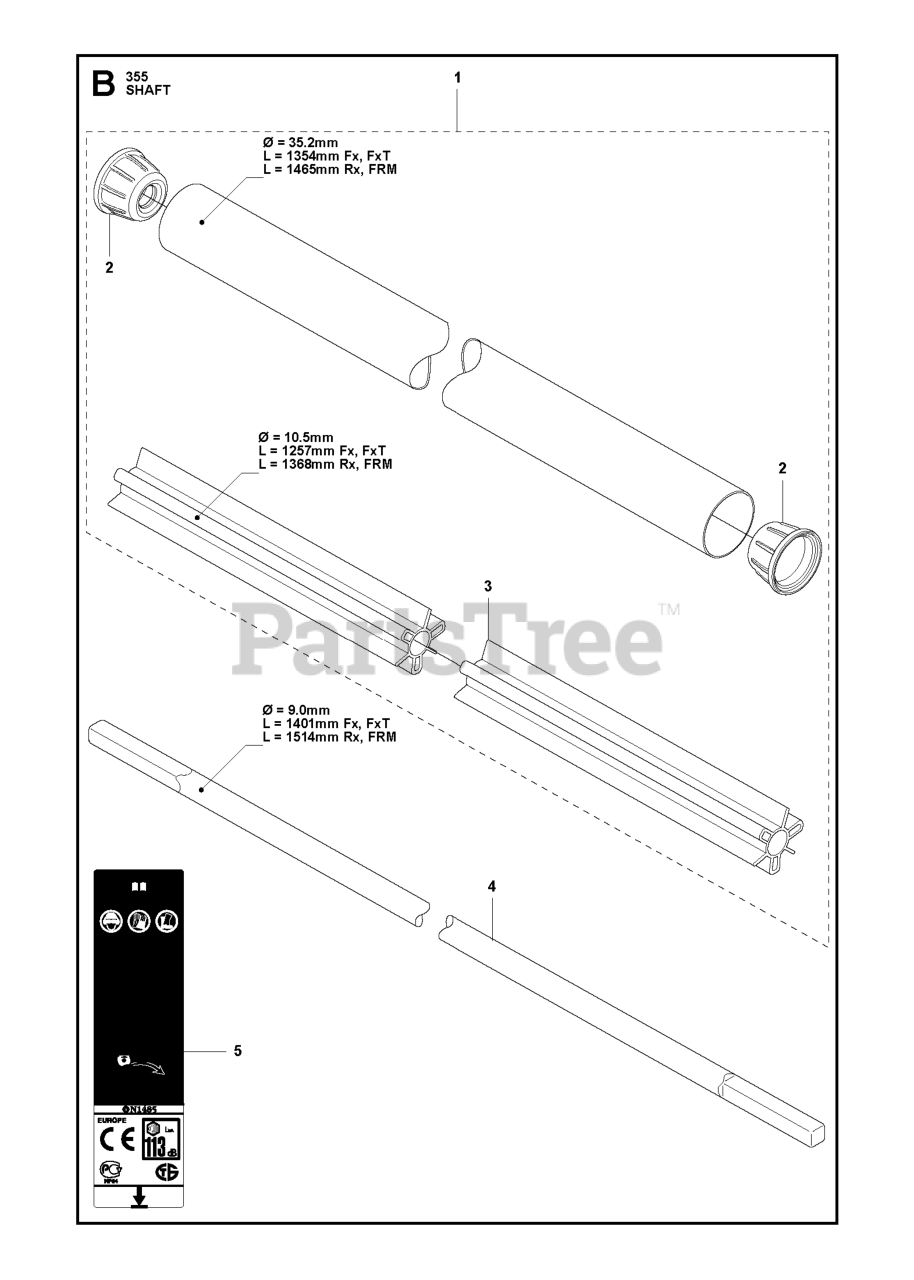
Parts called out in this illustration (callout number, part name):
1	TUBE DRIVESHAFT ASSY
2	RP SPACER
3	BEARING SHAFT
4	DRIVE SHAFT
5	LABEL WARNING TRIMMERS AND BRU
